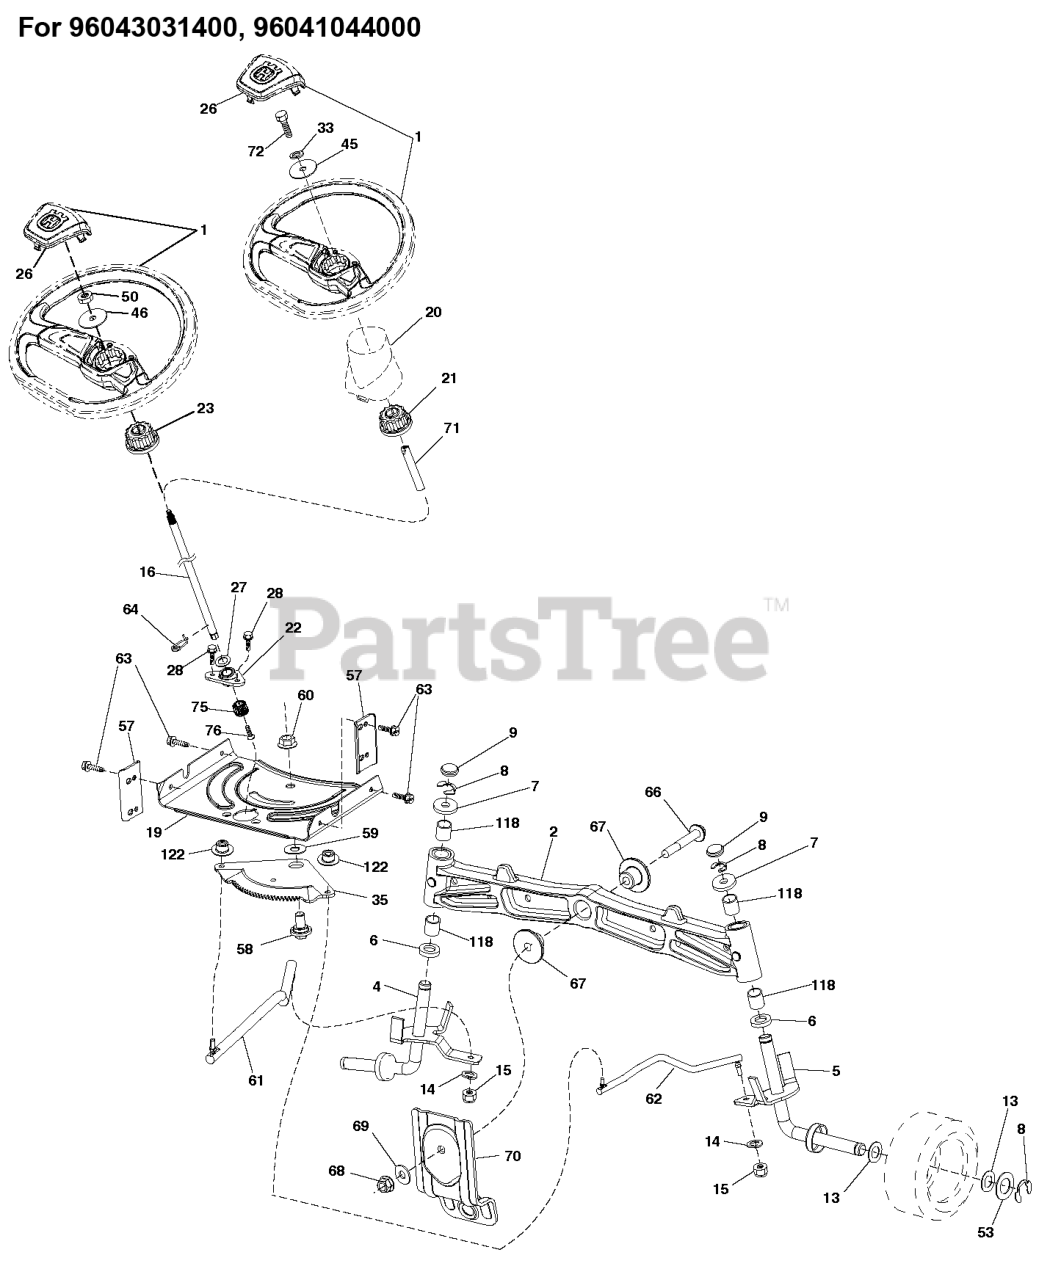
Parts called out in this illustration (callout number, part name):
1	Service Kit
2	AXLE.CAST.IRON
2	AXLE.SVC.ASM CAST IRON.TEX
4	SPINDLE.WELDED.LH.15"TEX
5	SPINDLE.WELDED.RH.15"T
6	WASHER THRUST
9	CAP.SPINDLE.BLACK
15	NUT CROWNLOCK 3/8-24
16	SHAFT.STEER.2HIGH.SPLND.PLATED
16	3 HIGH.SHAFT-ZINC.PLATED
19	PLATE.STEER.DDL.NLT/NG
20	STEERING.BOOT.HUSQ.LT
21	ADAPTER, WHEEL STNG..
22	BEARING.SHAFT.STEER.LOWER.625
23	ADAPTER.WHEEL.STEER.SPLND.ALUM
28	SCREW, 3/8-16X3/4
33	WASHER SPRING LOCK WASHER WITH
33	WASHER.LOCK.HVY.HLCL.SPR.5/16
35	GEAR.SECTOR.PLATE.DDL.
45	Washers
46	WASHER.3/8ID.2-3/8OD.12GA.PLTD
50	NUT LOCK FLG 3/8-16 UNC
53	WASHER.HARDENED
57	BRACKET.UPSTOP.TEX
58	BOLT.SHOULDER.SECTOR.P
59	WASHER.THURST.SECTOR.S
60	NUT FLANGE LOCK 5/8-11
61	Links
62	Links
63	SCREW
64	RETAINER.CLIP.SPRING.S
66	BOLT HEX FGHD 7/16-14 X 3 SERR
67	BUSHING.PM.FRONT AXLE
68	NUT.LOCK.FLANGE.7/16
69	WASHER.1.5X.505X.118
70	BRACKET.FRT.DECK.SUSP.RR.MT431
71	SHAFT.EXTEN.STRG.SPLINE
72	Bolts
75	PINION.ZINC PLATED
76	SCREW HEAD SOCKET LRVB
118	BUSHING, AXLE CAST
122	CAP.GEAR.SECTOR.TEX
